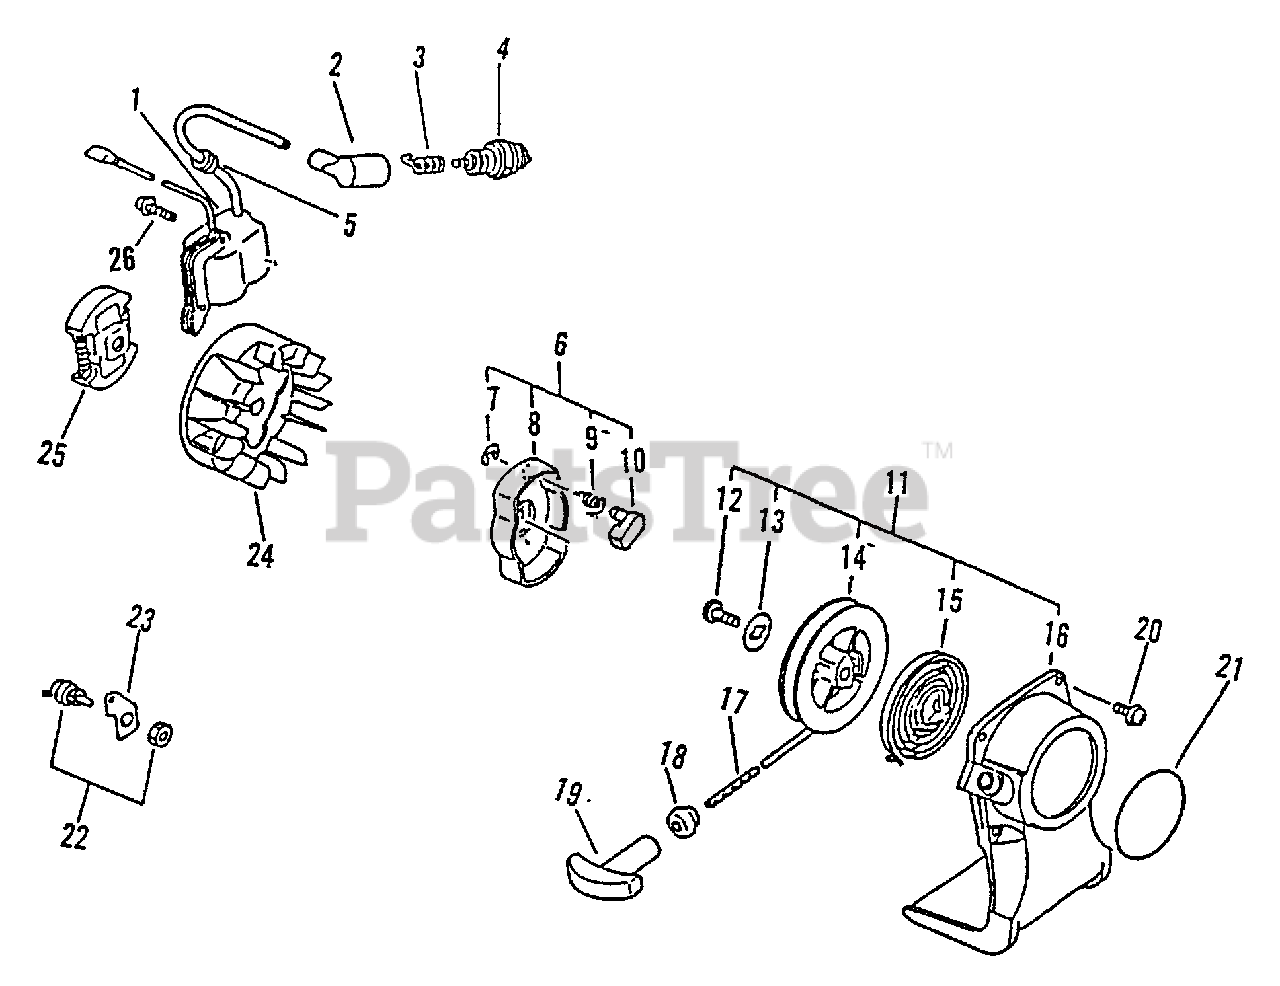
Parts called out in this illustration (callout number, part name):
1	COIL, IGNITION
2	CAP, SPARK PLUG
3	TERMINAL, SPARK PLUG
4	SPARK PLUG - BPM7A
4	SPARK PLUG - BPMR7A
6	STARTER PAWL ASSY
7	E-RING 4
8	CATCHER, PAWL
9	SPRING, RETURN
10	PAWL, STARTER
11	STARTER ASSY
13	WASHER
14	REEL, ROPE
15	SPRING, RECOIL
16	CASE, STARTER - BLUE
17	ROPE, STARTER
18	GUIDE, ROPE
19	GRIP, STARTER
20	SCREW 4×16
21	LABEL, ECHO
22	SWITCH, ON-OFF
23	BRACKET, SWITCH
24	FLYWHEEL
25	CLUTCH ASSY
26	SCREW 4×22
